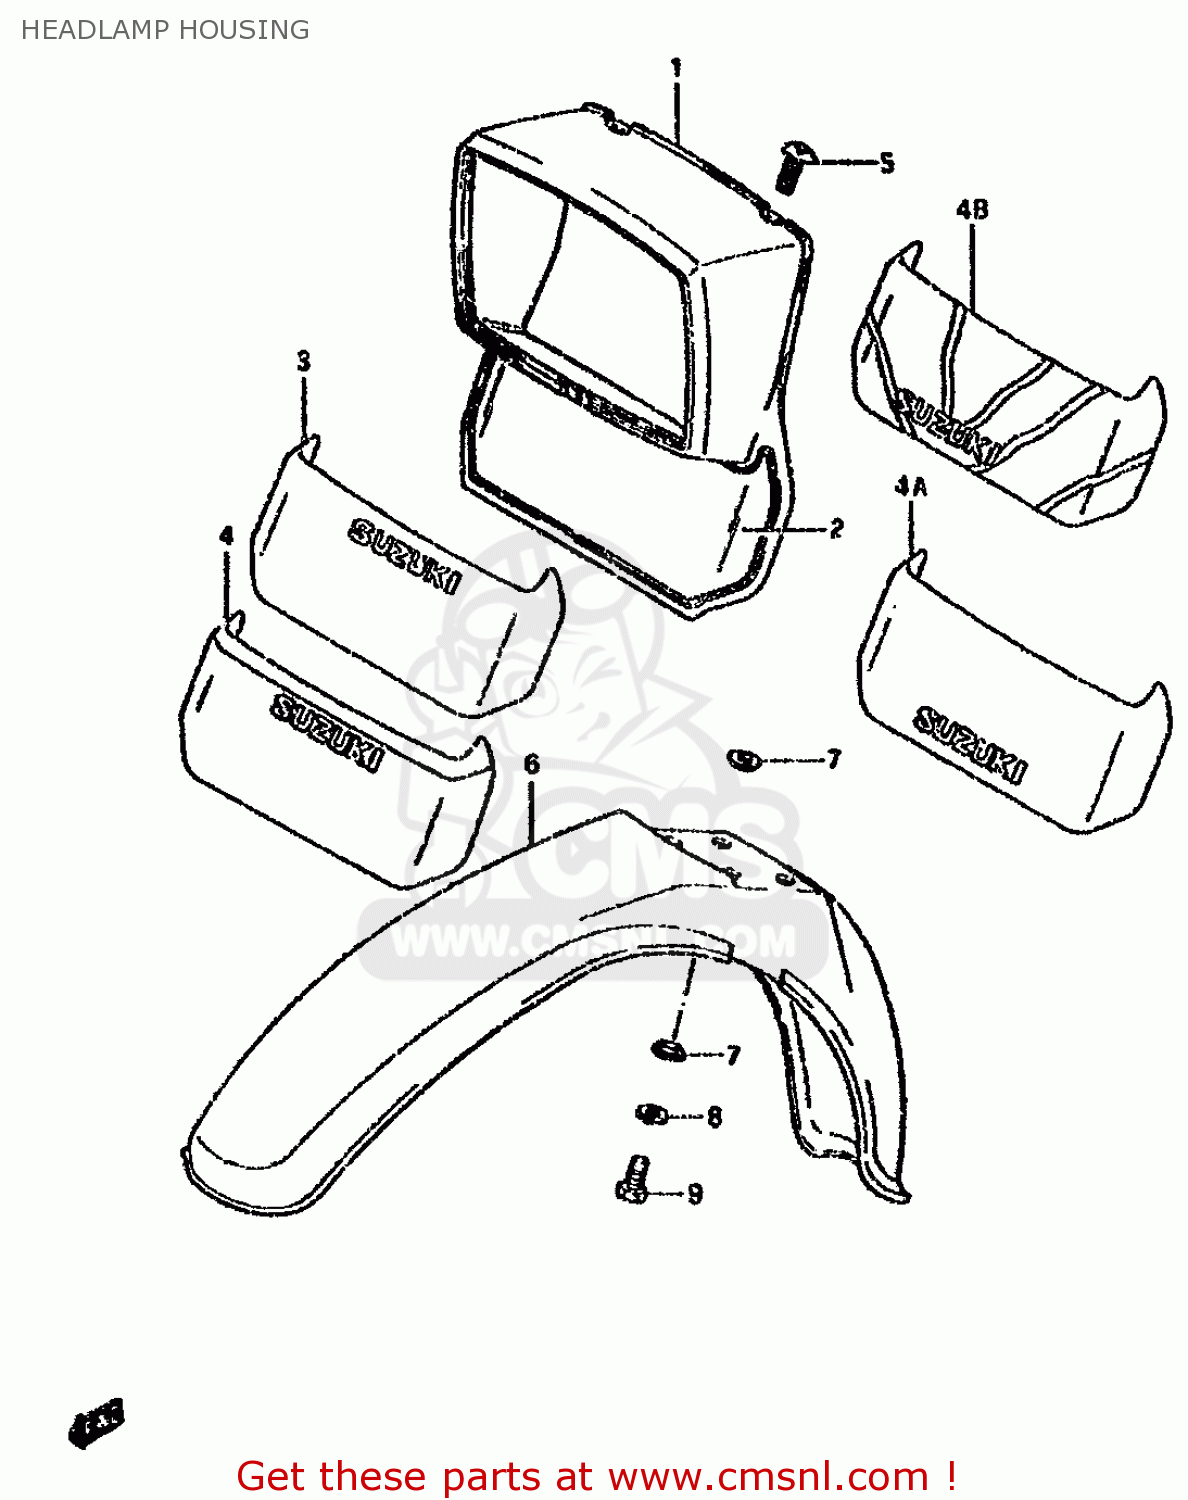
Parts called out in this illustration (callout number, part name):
1	HOUSING,HEADLAMP
2	EMBLEM,FRONT NUMBER PLATE
3	EMBLEM,FRONT NUMBER PLATE
4	TAPE,HEADLAMP HOUSING
4A	TAPE,HEADLAMP HOUSING
4B	TAPE,HEADLAMP HOUSING
5	SCREW 6X12
6	FENDER,FR
7	SPACER
8	WASHER,LOCK
9	BOLT
